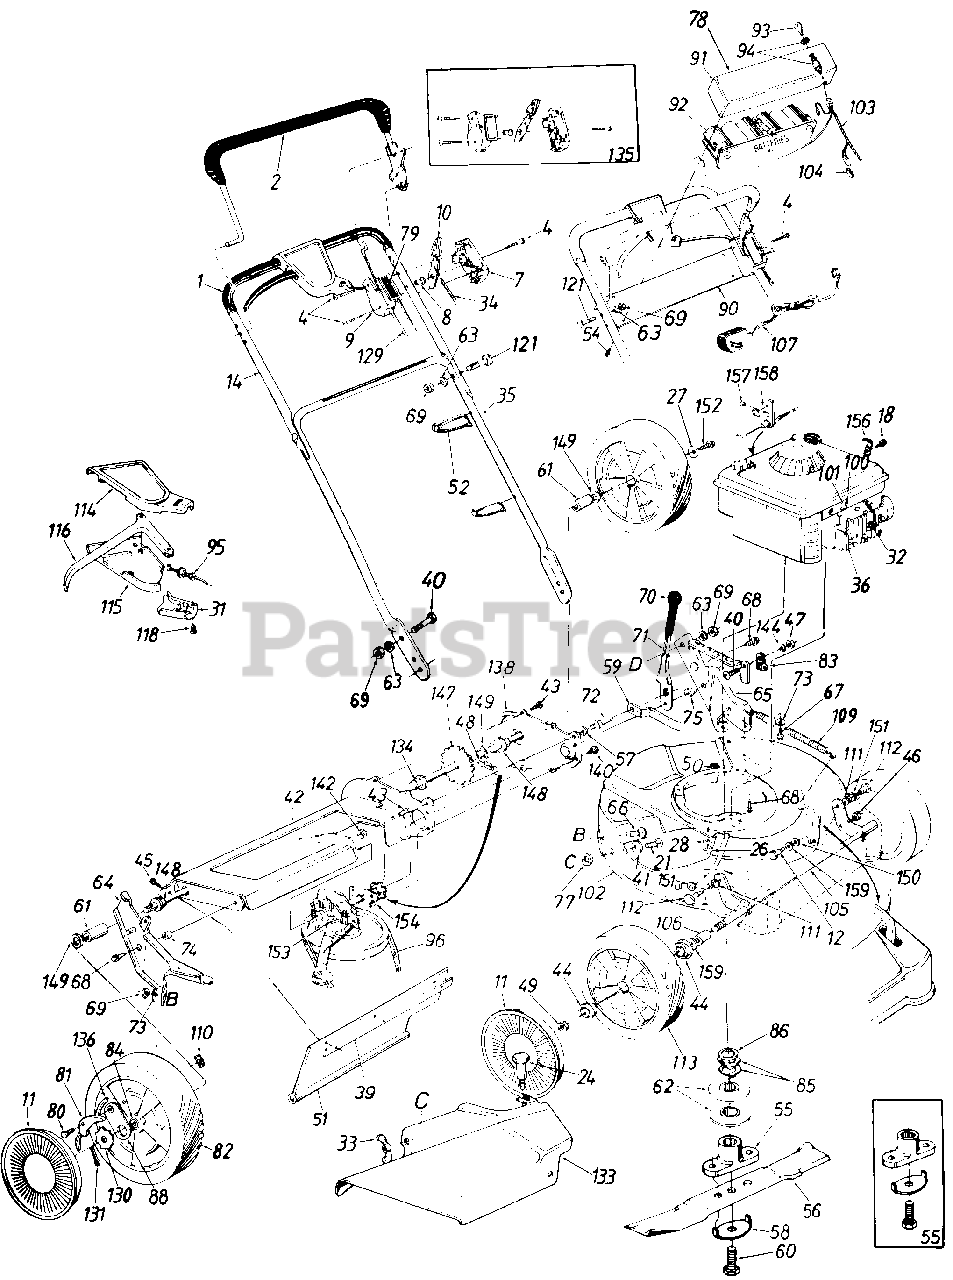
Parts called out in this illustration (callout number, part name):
1	Foam Grip
2	Control Handle Ass'y.-L.H.
4	Truss Mach. Scr. #12 x 1.50" Lg.
7	Control Panel Half
8	Control Disc Pin
9	Clutch Panel Half
10	Throttle Control Lever
11	Hub Cap
12	Shoulder Bolt .5" Dia. x .295
14	Upper Handle-Painted
18	Hex B-Tap Scr. #10 x .38" Lg.
21	Carriage Bolt 1/4-20 x .62"
21	Hex Bolt 1/4-20 x .50" Lg.
24	Shoulder Bolt .312 Dia. x .18 Lg.-Special
26	Hex Nut 1/4-20 Thd.
27	Bell-Wash. 1/4" I.D.
28	L-Wash. 1/4" I.D.
31	S.P. Control Cover
32	Spark Plug Insulator
33	Wing Nut w/Washer
34	Throttle Control Wire 58"
36	Engine
39	Retaining Strip
40	Truss Mach. Scr. 5/16-18 x .75" Lg.
41	Fl-Wash. .344" I.D. x .62"
44	Flange Ball Bearing 1/2" I.D.
45	Hex AB-Tap Scr. 1/4 x .62"
46	Hex Jam Nut 3/8-16 Thd.
47	Hex Patch L-Nut 3/8-24 Thd.
48	#48 Chain .500" Pitch x 30 Links
49	Hex L-Nut 1/2-20 Thd.
51	Rear Flap 3.75" x 17.30" Lg.
52	Cable Tie
54	Hex AB-Tap Scr. 1" Lg.
55	Blade Adapter Kit
56	21" Blade
57	L-Wash. 3/8" I.D.
58	Blade Bell-Wash. .44" I.D. x 2.38"
59	Height Adj. Rod 19.42" Lg.
60	Hex Bolt 7/16-20 x 1.5" Lg. (Grade 5)
61	Spacer .513" I.D. x .703" O.D. x .69" Lg.
62	Serrated Pulley Half
63	L-Wash. 5/16" I.D.
64	R.H. Handle Wheel Brkt. Ass'y.
65	L.H. Handle Wheel Brkt. Ass'y.
66	Carriage Bolt 5/16-18 x .62"
67	Hex Wash. Hd. B-Tap Scr. 5/16-18
68	Hex Wash. Hd. TT-Tap Scr. 3/8-16
69	Hex Nut 5/16-18 Thd.*
71	Height Adj. Lever
72	Shld. Pin 3/8-24 x 1.43" Lg.
73	Bell-Wash. 5/16" I.D.
74	Spacer.383" I.D.
75	Shld. Spacer .500" Dia.
77	Bolt Retainer 1/4 X .50" O.D.
78	Instruction Label
79	Control Label
80	Shld. Scr. .342" Dia. x .268
82	Wheel Ass'y. Comp.
83	Clamp
84	Bearing 1/2" I.D.
85	Wave Washer 1.005" I.D.
86	Serrated Washer 1.0" I.D.
88	Pawl Plate
90	Lower Battery Tray
91	Upper Battery Tray
92	12 Volt Battery
94	Key Switch
95	S.P. Cable x 48" Lg.
96	V-Belt
100	Hex B-Tap Scr. #10 x .62"
101	Cable Clamp
102	483/N 21" Deck Ass'y.
103	Wire Harness
105	Front Axle Ass'y.
106	Sleeve .526" I.D. x .690" O.D. x .880" Lg.
107	Battery Charger
109	Extension Spring .75" O.D. x 8.0" Lg.
110	Flat Weld Nut 1/4-20 Thd.
111	Intern. L-Wash. 3/8 I.D.*
112	Shld. Bolt .575" Dia. x .42
113	Wheel Ass'y. Comp.
114	Self-Propelled Control Cover
115	Self-Propelled Control Cover
116	Control Lever
118	Fl-"C"-Sunk Hd. Tap Scr. #10 x .75" Lg.
121	Curved Carr. Bolt 5/16-18 x 1.38" Lg.
129	Control Cable 46" Lg.
130	Ratchet Wheel 1.62n O.D.
131	Cotter Pin 1/8" Dia. x 1.00" Lg.*
133	Side Chute Deflector Ass'y.
134	Hex Flange Bearing
135	Kit-Control Housing Comp.
136	Spring-Nylon
142	Hex Jam Nut 3/8-24 Thd.
144	Fl-Wash. .385" I.D. x .87"
147	Rear Shaft Ass'y. 21.94" Lg.
148	Hex Flange Bearing .506" I.D. Plastic
149	Fl-Wash. .531" I.D. x .930"
150	Bell-Wash. .515" I.D. x 1.0" O.D.
151	Flanged Nyiiner Brg.
152	Hex Bolt 1/4-20 x .62" Lg. (Grade 5)
153	Transmission Comp.
154	Hex Bearing Cup
156	Cable Clamp
157	Pop Rivet .156" Dia.
158	Cable Bracket
159	Fl-Wash. .51" I.D. x .75" O.D.
